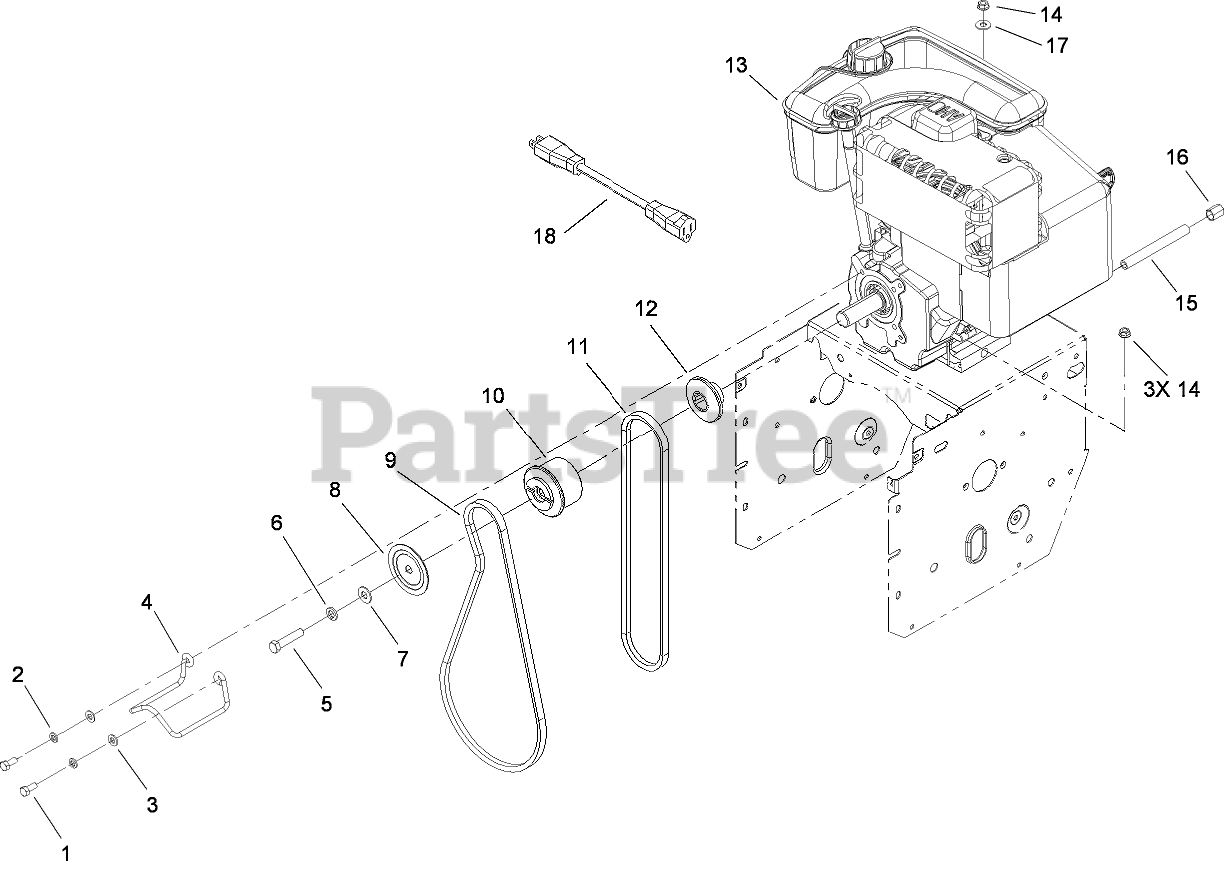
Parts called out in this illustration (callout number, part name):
1	SCREW-HH
2	WASHER-LOCK
3	WASHER-PLAIN
4	GUIDE-BELT
5	SCREW-HH
6	WASHER-LOCK
7	WASHER-FLAT
8	SHEAVE-HALF, IMPELLER
9	BELT-V
10	PULLEY-ENGINE, CENTER
11	V BELT-TRACTION
12	SHEAVE-HALF, TRACTION
14	NUT-HF
15	NIPPLE-PIPE
16	CAP-PIPE
17	WASHER-FLAT
18	CORD-EXTENSION
